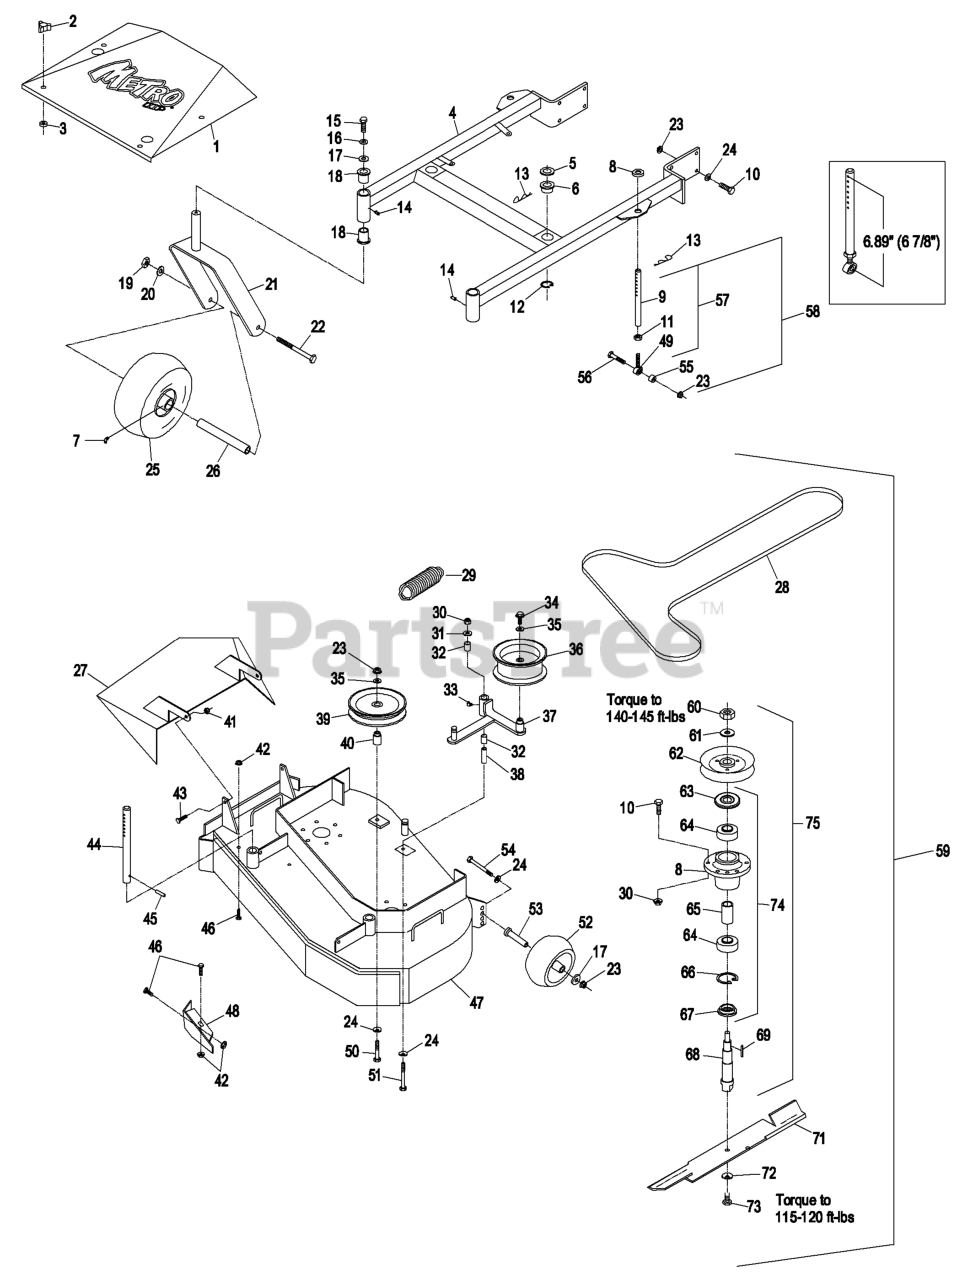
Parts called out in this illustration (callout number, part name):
1	SHIELD W/DECAL,MHP36
2	KNOB-3 PRONG
4	DECK SUPPORT W/BSHGS 36"
5	SPACER-DECK SUPPORT
6	BUSHING-DECK
7	FITTING-GREASE
9	LINK,SUPPORT
10	SCREW-HH
11	NUT-HEX
12	RING-RETAINING
13	PIN,HAIR COTTER
14	FITTING-GREASE
15	SCREW-HH
16	WASHER-LOCK
18	BEARING-FLANGED
19	NUT-HH
20	WASHER-LOCK
22	SCREW-HH
23	NUT-HHF, WHIZ
24	WASHER-BELLEVILLE
26	SPACER FRONT CASTER
27	WLD,DISCHARGE CHUTE 36/48
28	BELT,DECK DRIVE
30	NUT-LOCK, NI
31	WASHER-FLAT
32	SLEEVE-BEARING
33	FITTING-GREASE, 90 DEG
34	SCREW-HHF
35	WASHER-FLAT
37	Arm, Weldmt
38	BUSHING-PIVOT, IDLER
39	PULLEY-IDLER
40	BUSHING-IDLER
41	NUT-LOCK, NI
43	SCREW-HH
44	ROD,DECK SUPPORT
46	SCREW-HH
47	ASM,DECK W/DECALS TTHP/MH
49	BALLJOINT
50	SCREW-HH
51	SCREW-HH
52	ROLLER-SCALP, ANTI
53	BUSHING-ROLLER
54	SCREW-HH
56	SCREW-HH
59	Assy, Cutting Deck Complete
62	SHEAVE,W/HUB 5.72
63	GUARD-BEARING, TOP
64	BEARING-JACKSHAFT
65	SPACER-BEARING
66	RING-SNAP
67	SPACER-GUARD, BOTTOM
68	SPINDLE,SHAFT
69	KEY-RECTANGLE
72	WASHER-SPRING
73	SCREW-CAP
76	KIT, SP CASTER WHEEL REPL
